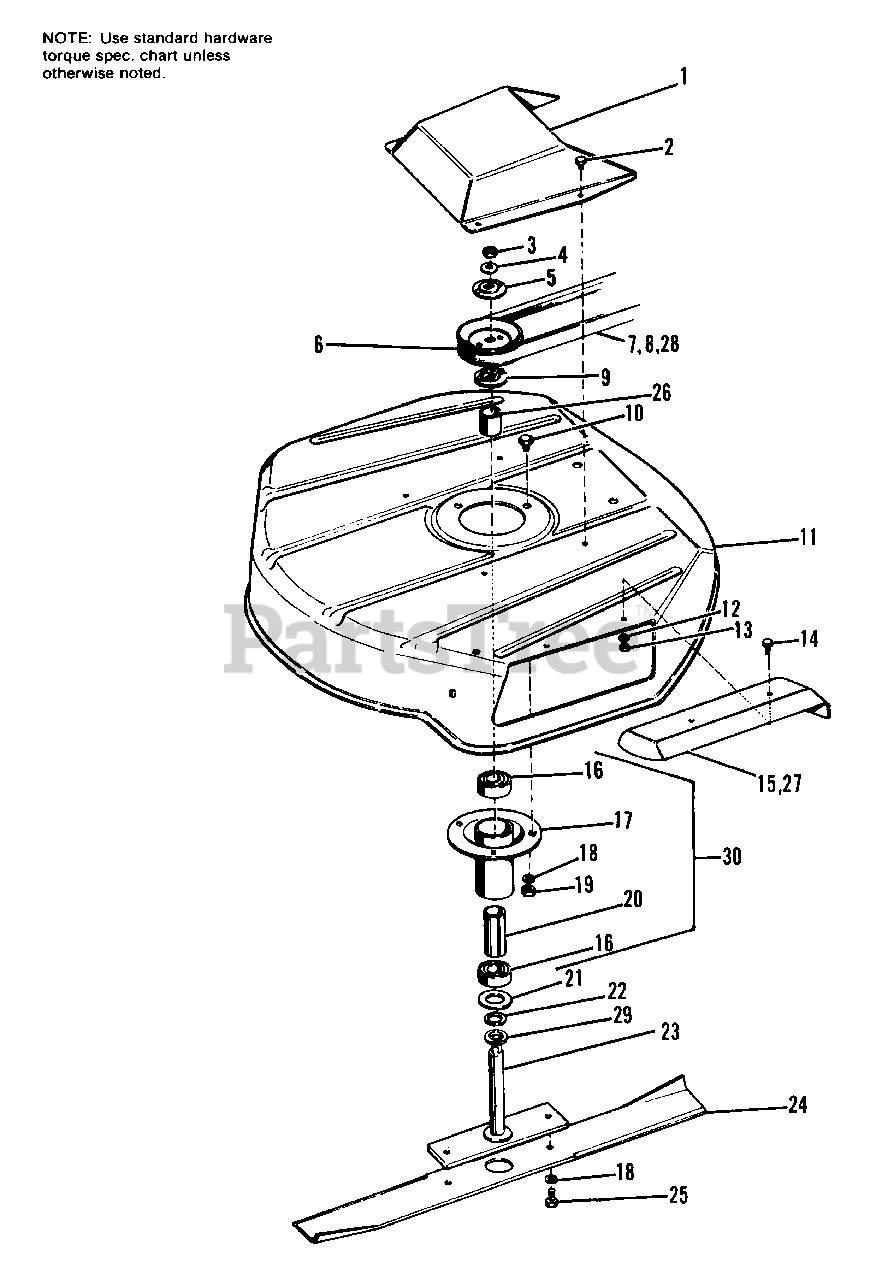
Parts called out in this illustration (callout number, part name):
1	GUARD, Belt
2	SCREW, Hex, Washer Hd, Taptite, 1/4-20 x 4 3/8
3	LOCKNUT, Hex, 3/8-16
4	WASHER, Plain, 5/16
5	WASHER, Special
7	BELT, V
8	BELT, V
10	CAPSCREW, Hex Hd, 3/8-16 x 3/4
11	HOUSING, 24"
12	LOCKWASHER, Ext., 1/4
13	NUT, Hex, Full, 1/4-20
14	CAPSCREW, Hex Hd, 1/4-20 x 1/2
15	DEFLECTOR
16	BEARING, Ball
17	TUBE ASSY, Arbor
18	LOCKWASHER, 3/8
19	NUT, Hex, Full, 3/8-16
23	ARBOR ASSY
24	BLADE, 24"
25	CAPSCREW, Hex Hd, 3/8-16 x 3/4
26	SPACER
27	DEFLECTOR
28	BELT, V
29	WASHER
30	ARBOR ASSY, W/Bearings & Hardware
